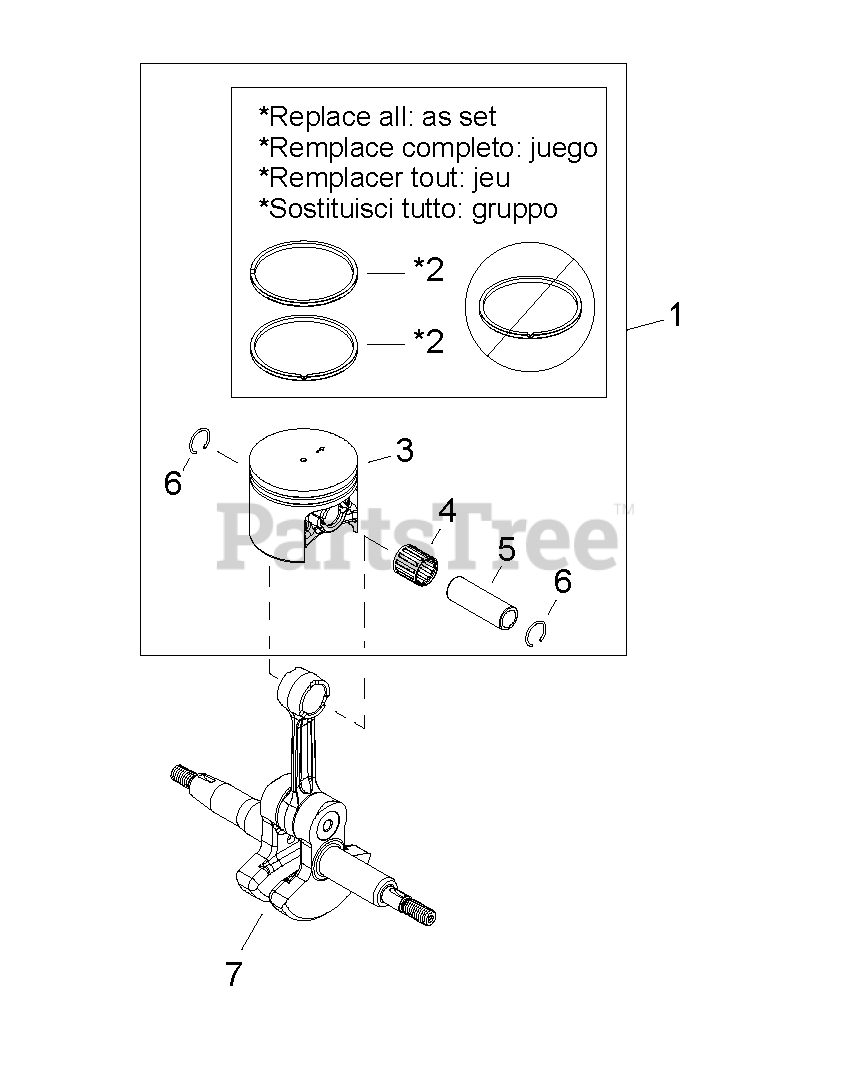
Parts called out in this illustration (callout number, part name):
1	PISTON KIT
2	RING, PISTON
3	PISTON
4	BEARING, NEEDLE 12
5	PIN, PISTON 12
6	RING, SNAP
7	CRANKSHAFT
